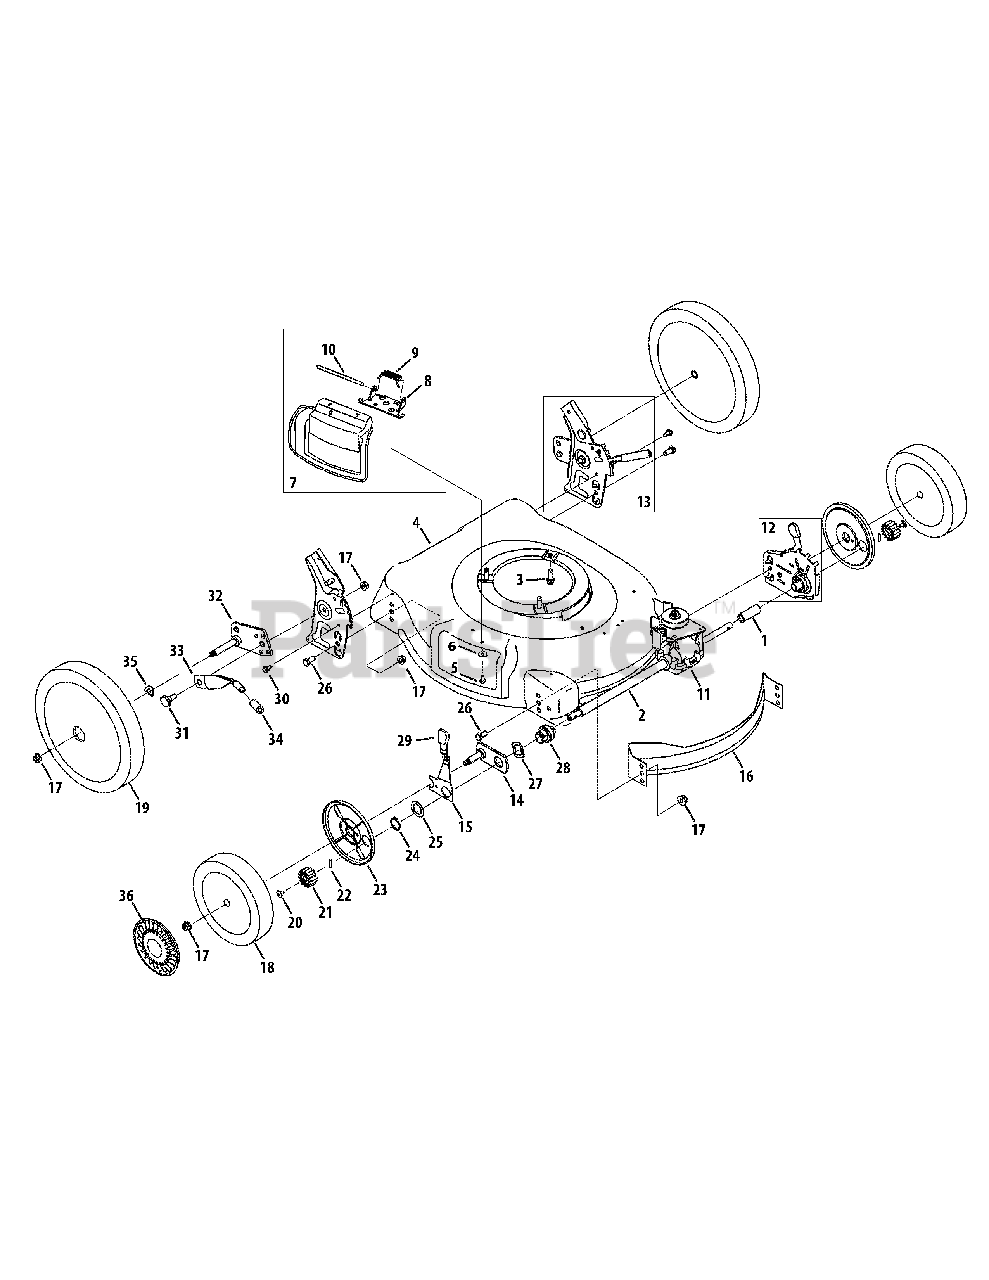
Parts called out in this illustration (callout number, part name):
1	Slev. Spacer, 1.8" Lg.
2	Slev. Spacer, 9.10" Lg.
3	TT Screw
5	TT Screw, 1/4-20 x 0.5
6	Bell Washer
7	Hinged Mulch Plug Assembly
8	Chute Deflector Adapter
9	Torsion Spring
10	Hinge Pin
11	Transmission Assembly
12	Height Adj. Assembly - LH
12	Height Adj. Assembly - RH
13	Handle Bracket Assembly - LH
13	Handle Bracket Assembly - RH
14	Pivot Plate Assembly
15	Front Lever - RH
15	Front Lever - LH
16	Front Baffle
17	Flange Lock Nut, 3/8-16
18	Front Wheel, 8x 2.125
19	Rear Wheel, 12 x 2.125, Yellow
19	Rear Wheel, 12 x 2.125, Gray
20	Screw, 1/4-20 x .390
21	Gear 14T FWD - RH
21	Gear 14T FWD - LH
22	Dowel Pin
23	Wheel Dust Cap
24	Snap Ring
25	Flat Washer
26	Hex Screw, 3/8-16 x .75
27	Wave Washer
28	Bearing Assembly
29	Adjustment Knob
30	TT Screw w/washer, 1/4-20 x .625
31	Shoulder Screw, .500 Dia. x .385
32	Pivot Arm Assembly - RH
32	Pivot Arm Assembly - LH
33	Rear Spring Lever
34	Foam Grip
35	Washer, Spring, .500 x 1.00 x .022
36	Hubcap
